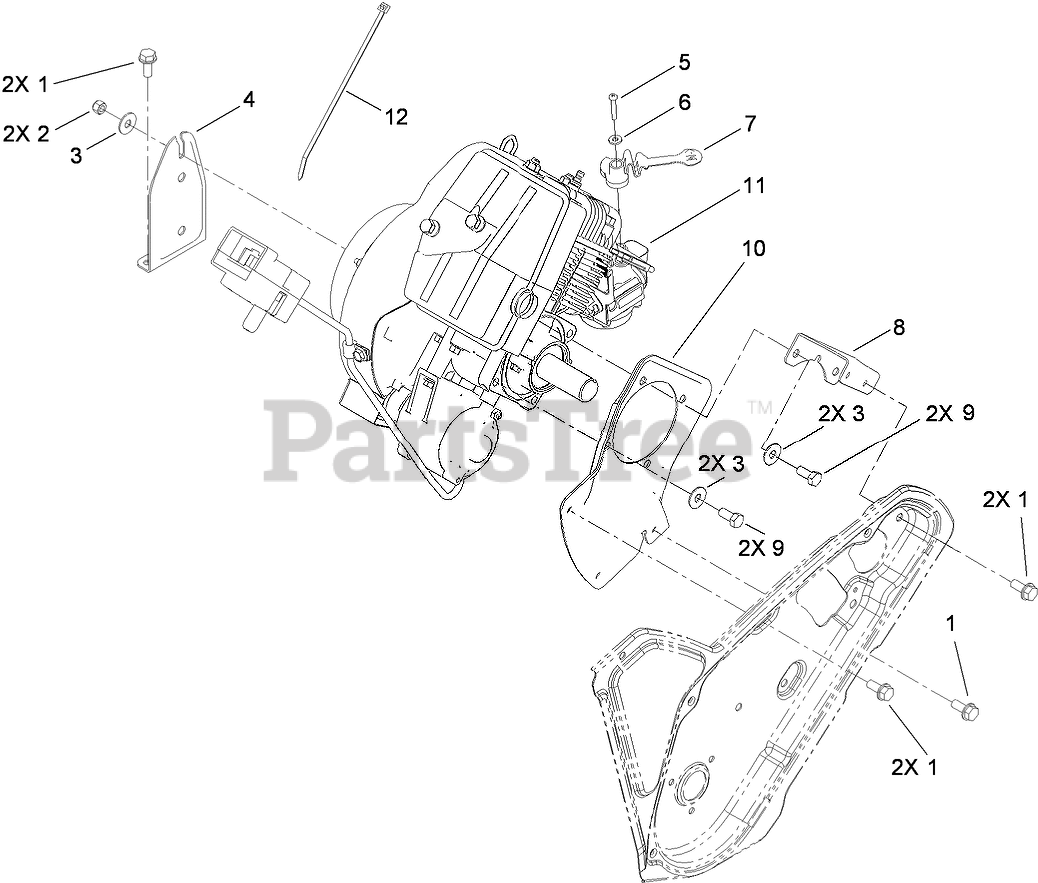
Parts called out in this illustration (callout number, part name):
1	SCREW-HWHTF
2	NUT-LOCK, NI
3	WASHER-BELLEVILLE
4	BRACKET-RECOIL
5	SCREW-PPH, PLASTITE
6	WASHER-FLAT
7	LEVER-CHOKE
8	SUPPORT-ENGINE, SIDE
9	SCREW-HH
10	PLATE-ENGINE, PTO
12	TIE-CABLE
